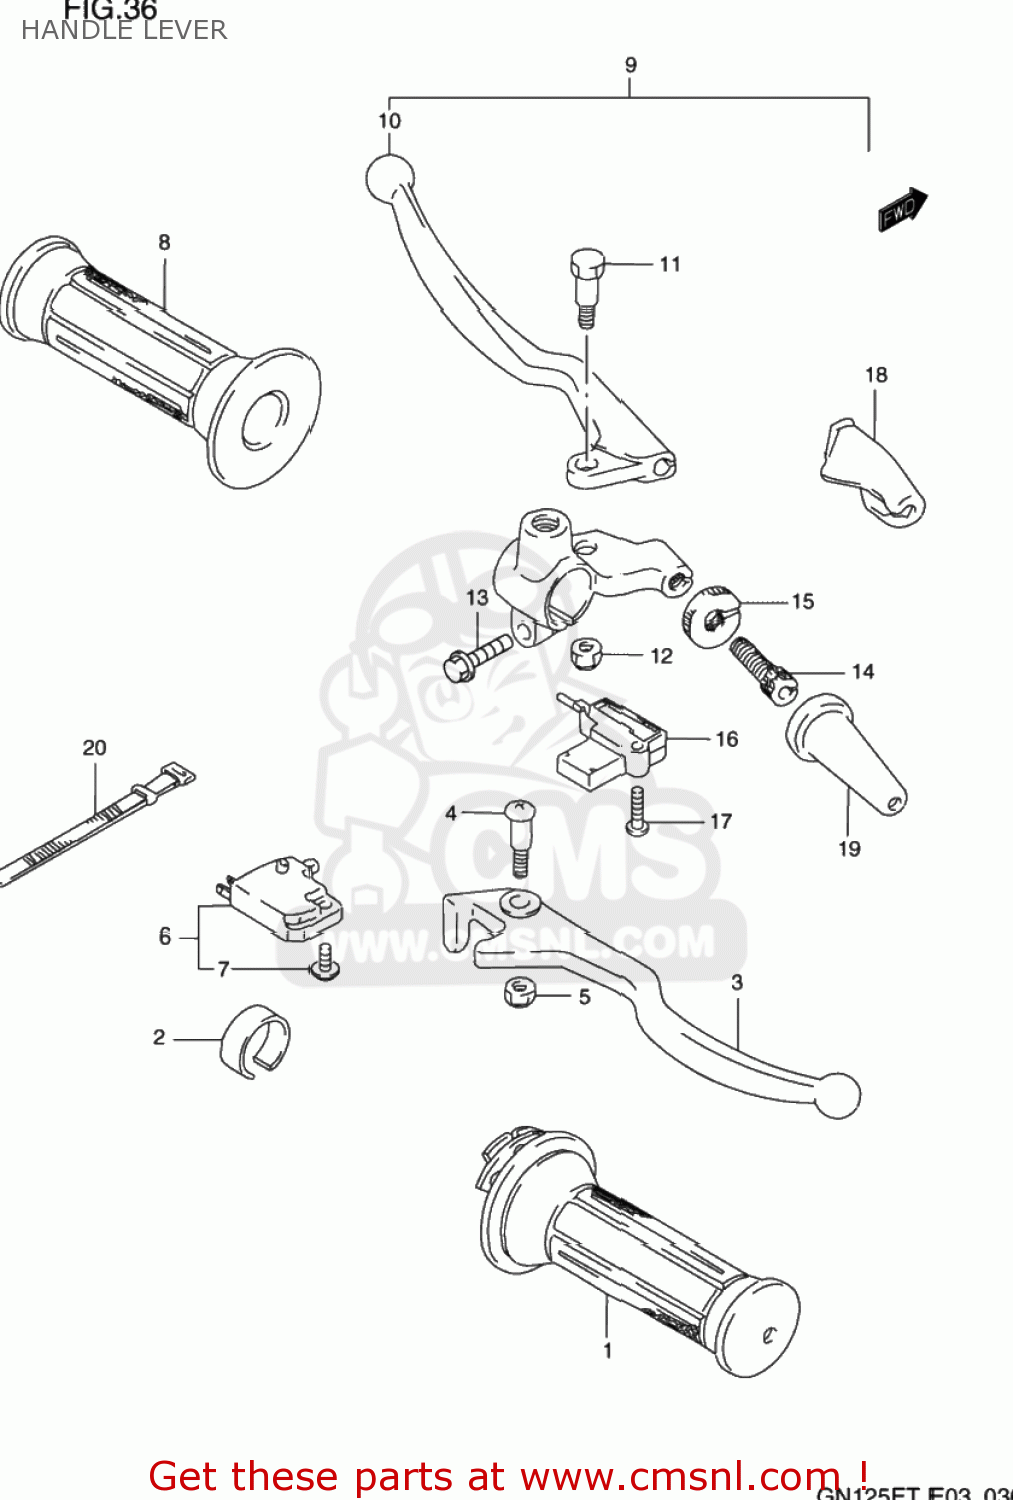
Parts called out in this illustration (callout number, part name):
1	GRIP,THROTTLE
2	SPACER,HANDLE SWITCH,R
3	LEVER,BRAKE
4	SCREW
5	NUT
6	SWITCH ASSEMBLY,STOP
7	SCREW
8	GRIP,L
9	LEVER ASSY,CLUTCH
10	LEVER,CLUTCH
11	BOLT,LEVER SET
12	NUT
13	BOLT 6X20
14	ADJUSTER,WIRE
15	NUT,LOCK
16	SWITCH,CLUTCH
17	SCREW
18	COVER,CLUTCH LEVER
19	BOOT,CLUTCH CABLE
20	CLAMP(L:120)
